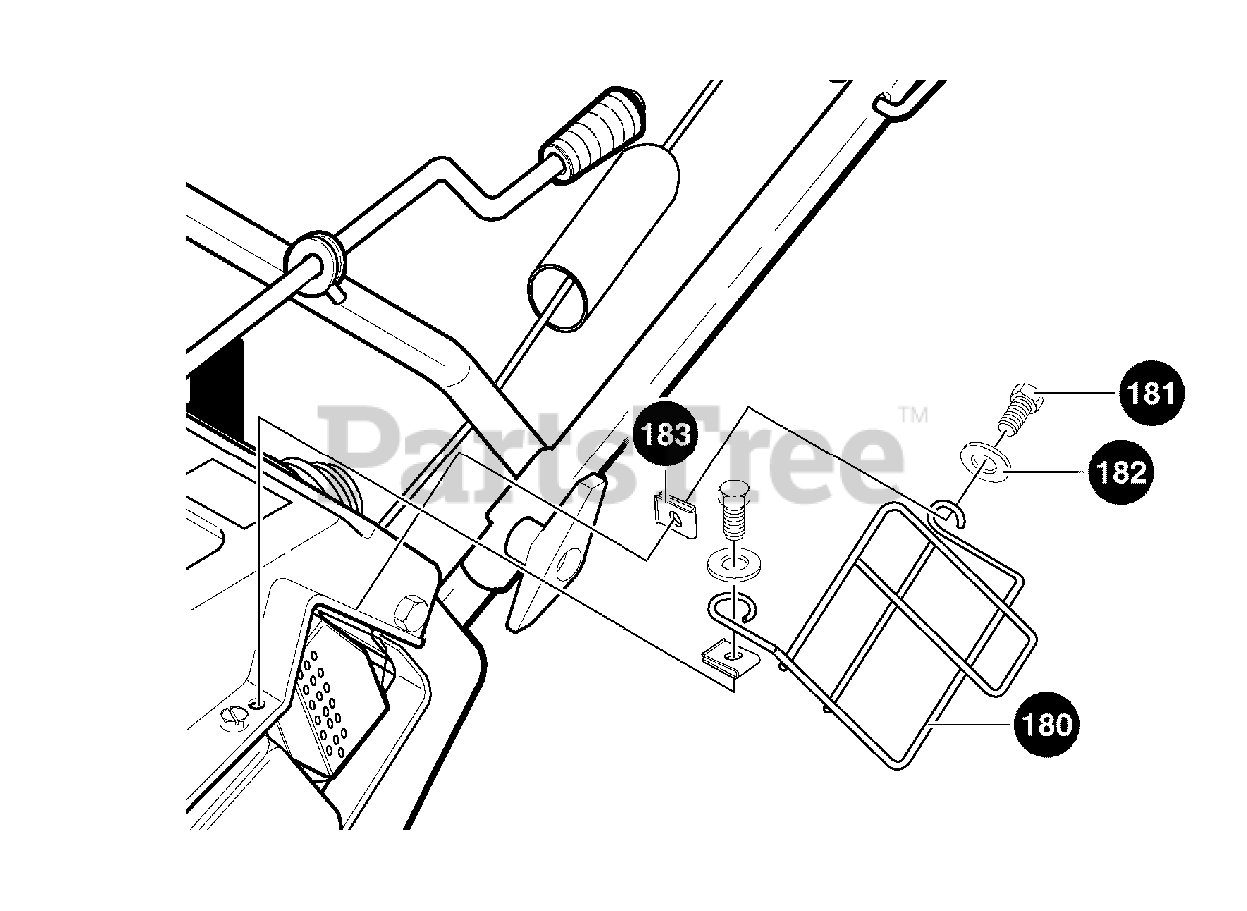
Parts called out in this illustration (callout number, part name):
180	GUARD, MUFFLER -EXPT
181	SCREW
182	WASHER, FLAT
